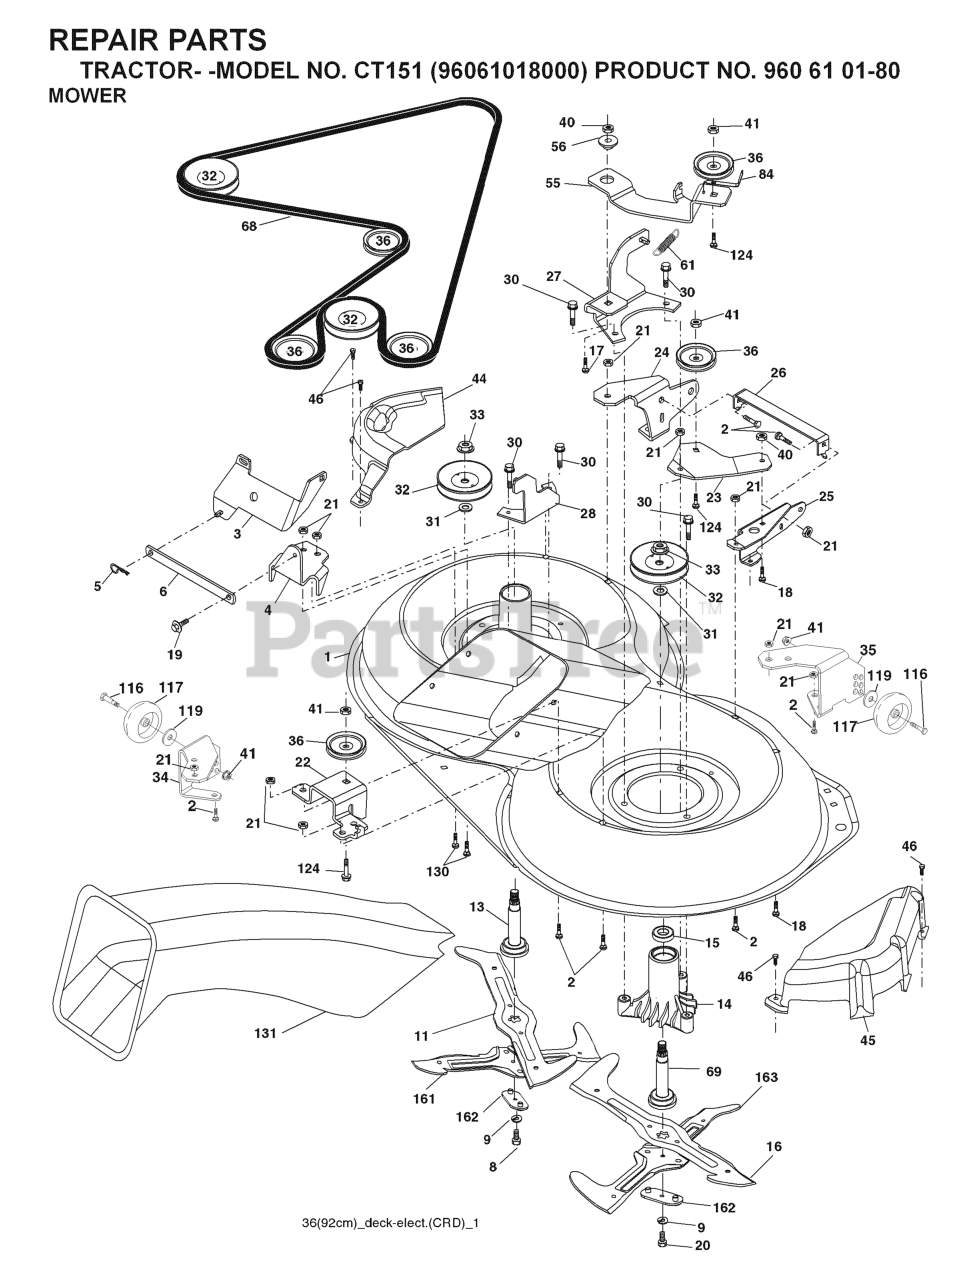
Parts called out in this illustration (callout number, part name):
2	BOLT
8	WASHER
11	SCREW IHCSFM
12	LOCKNUT M5
